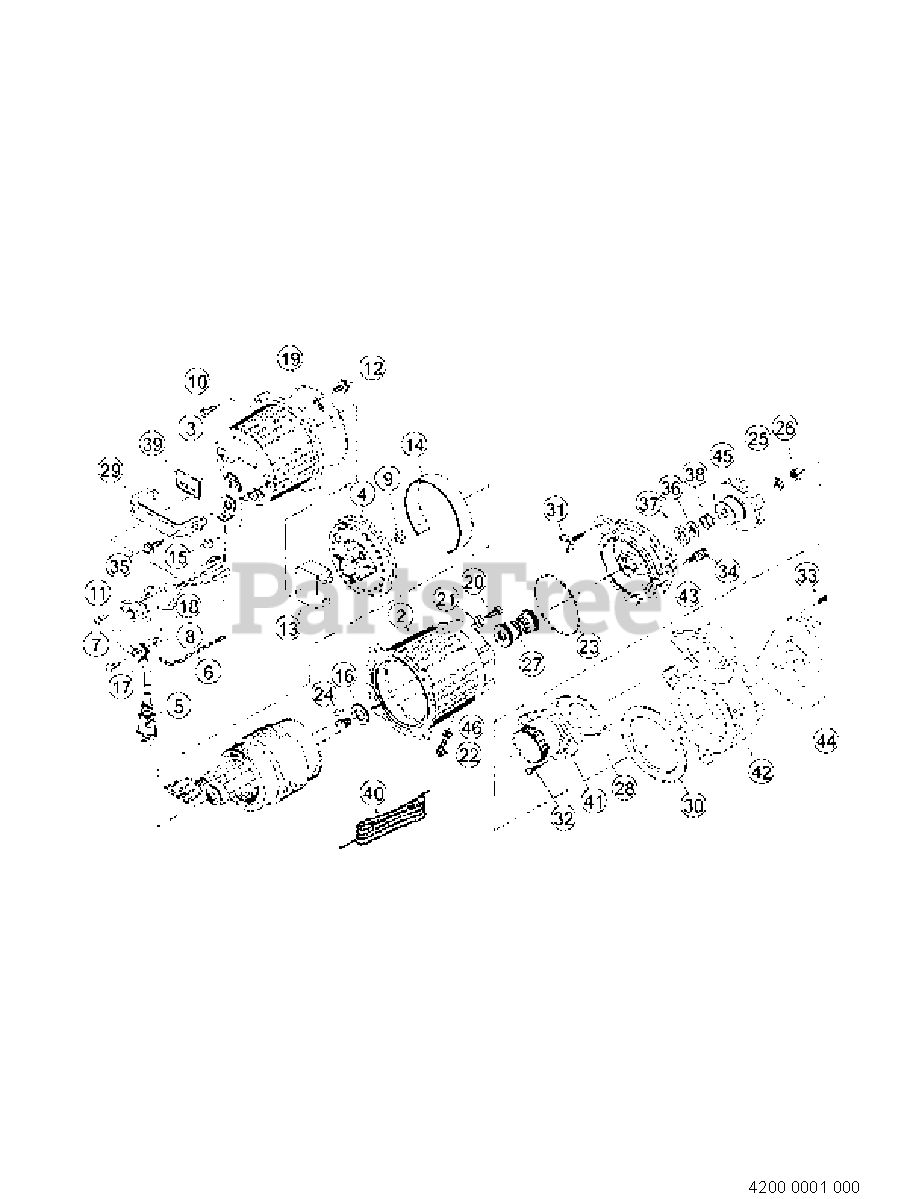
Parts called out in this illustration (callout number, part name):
2	FRAME
3	HEAD COVER
4	BRACKET
6	CHAIN AY
7	SCREW
8	HEX NUT
9	WAVE WASHER
10	HEX BOLT
11	SCREW
12	SCREW
13	CONDESER
14	SUPPORTER
15	HEAD BUSHING
16	BEARING WASHER
17	CORD SUPPORTER
18	CORD BAND
19	HEAD GASKET
20	SCREW
21	SEAL RING
22	HEX SOCKET BOLT
23	O RING
24	KEY
25	SPRING WASHER
26	HEX NUT
27	MECHANICAL SEAL
28	DELIVERY GASKET
29	HANDLE
30	CASING GASKET
31	WING BOLT
32	HEX BOLT
33	HEX BOLT
34	HEX SOCKET BOLT
35	SCREW
36	THRUST WASHER
37	THRUST WASHER GASKET
38	OIL SEAL
39	LABEL
40	ROPE
41	DELIVERY FLANGE
43	FRONT BRACKET
44	BOTTOM PLATE
46	SEAL WASHER
